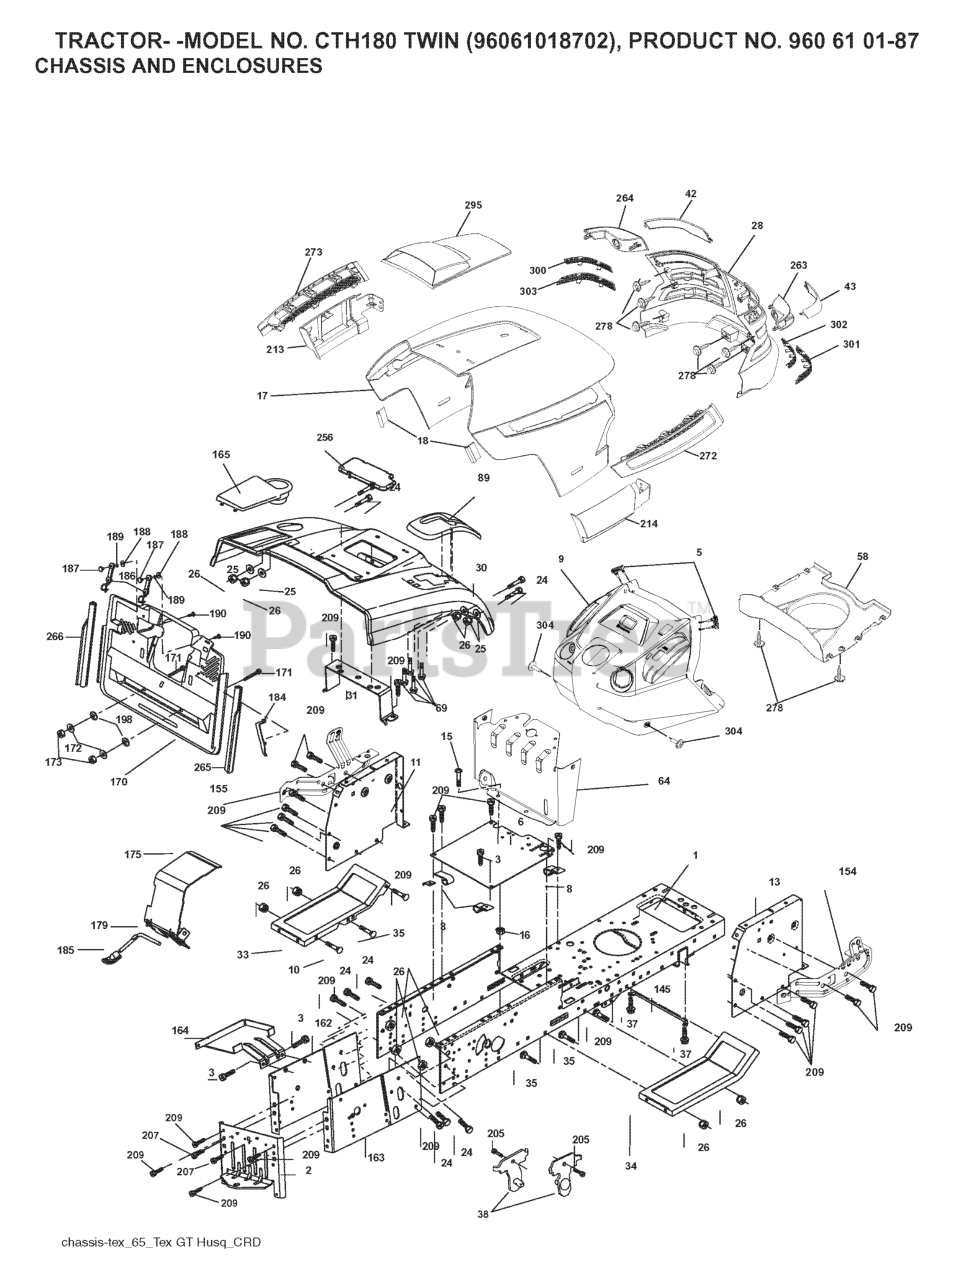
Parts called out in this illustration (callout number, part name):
2	DRAWBAR
3	SCREW 3/8-16X3/4
5	BUMPER DASH
6	PLATE
8	CLIP,INSULATOR
10	BOLT D
11	PANEL DASH LH
13	PANEL DASH RH
15	Screw, Machine, Truss Head 5/16-18 UNC x 3/4
16	NUT
17	HOOD
18	BUMPER.HOOD.TEX.HUSQVARNA
25	WASHER
26	NUT
28	GRILL.ASM.HUSQ.TG/CRD.W/TRIM
30	CONSOLE.CRD.AUTO.GRY
31	BRACKET SUPPORT FENDER
33	FOOTREST PNT LH
34	FOOTREST PNT RH
37	Screw 5/16-18 x 1/2 Hex, Self Tapping 5/16-18 x 1/2
38	BRACKET ASM PIVOT MOWER REAR
42	LENS.LH.TEX.GT.HUSQ.CL
43	LENS.RH.TEX.GT.HUSQ.CL
58	AIR.DUCT.HOOD.TEX.GT.HUSQ
69	SCREW.HI-LO.CONSOLE
89	CONSOLE.CRD.AUTO.GREY.2005
145	ROD.PIVOT.HOOD
162	BRACKET
163	BRACKET EXTEN CHASSIS RH CRD
165	RP.COVER.BATTERY.CRD.GREY
172	WASHER
175	DOOR TRAP
179	ROD PIVOT FBI
184	BRACKET.ACTUATOR.BAGGER.SRD
186	LATCH ASSY
187	WELDNUT
189	LOCKWASHER #10
190	SCREW
207	SCREW, 5/16-18 X 1/2
209	SCREW, 3/8-16X3/4
213	SKIRT.HOOD.SIDE.HUSQ.LH.GREY
214	SKIRT.HOOD.SIDE.HUSQ.RH.GREY
256	COVER FENDER CRD
263	BEZEL.RH.TEX.GT.HUSQ
264	BEZEL.LH.TEX.GT.HUSQ
265	SEALING
266	SEALING
272	VENT.SIDE.HOOD.HUSQ.RH.GREY
273	VENT.SIDE.HOOD.HUSQ.LH.GRAY
278	SCREW
295	VENT.ASM.HOOD.TOP.TEX.
300	INSERT.HEX.GRILL.HUSQ.
301	INSERT.HEX.GRILL.HUSQ.GREY
302	INSERT.HEX.GRILL.HUSQ.
303	INSERT.HEX.GRILL.HUSQ.
304	SCREW 14-20 X 5/8
